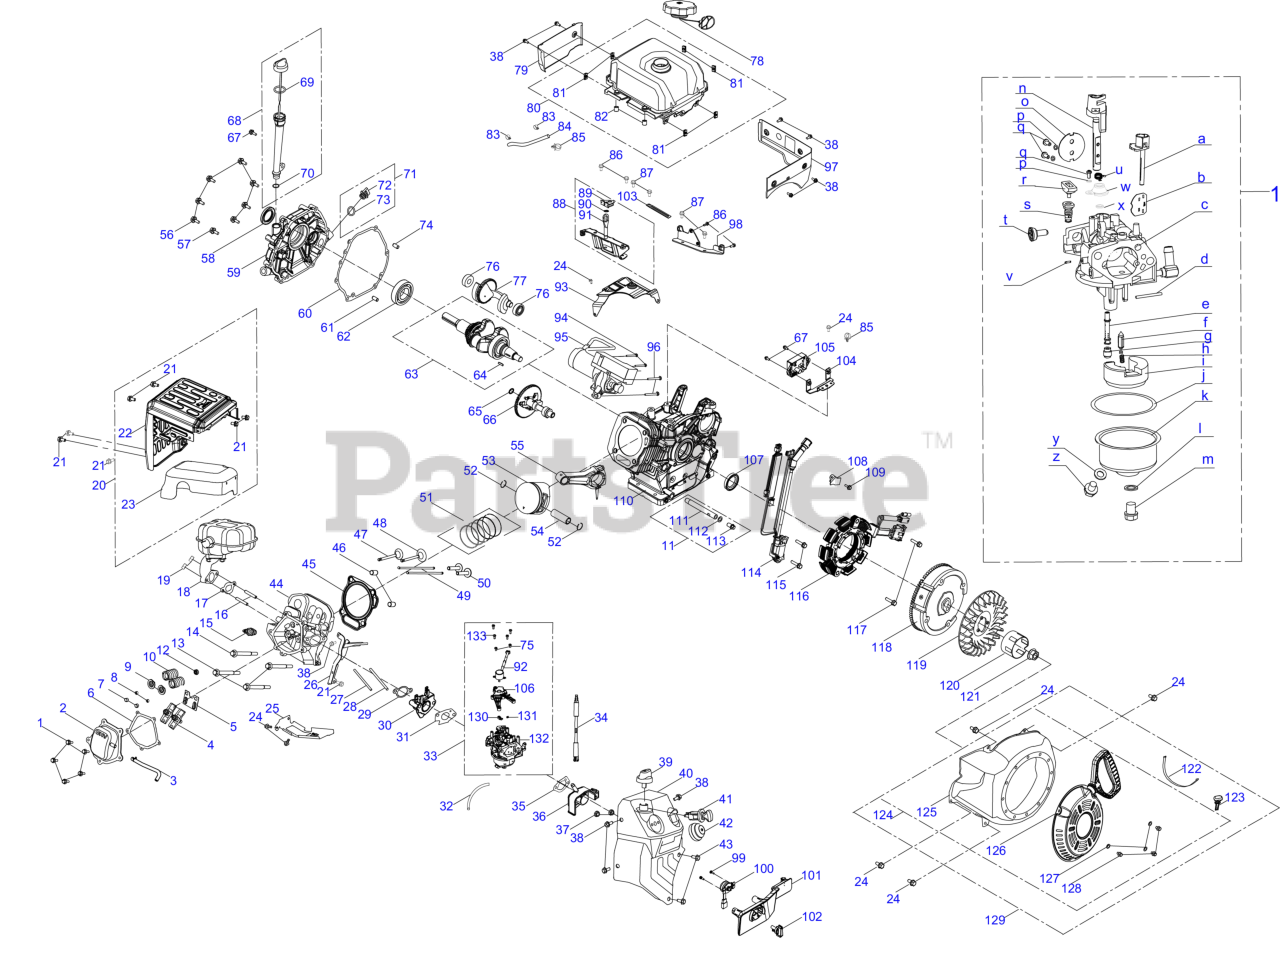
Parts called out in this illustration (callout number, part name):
1	BOLT M6 x 16
2	VALVE COVER
3	BREATHER HOSE
4	ROCKER ARM ASSEMBLY
5	PUSH ROD GUIDE
6	VALVE COVER GASKET
7	EXHAUST VALVE ADJUSTER
8	VALVE CAP
9	VALVE SPRING SEAT
10	VALVE SPRING
11	OIL DRAIN PIPE
12	INTAKE VALVE SEAL
13	SCREW M10-1.25 x 87 x GR10.9
14	SCREW M10-1.25 x 65 x GR10.9
15	SPARK PLUG (F6RTC/RN11YC/BPR6ES)
16	STUDS M8-1.25 x 48.5
17	MUFFLER GASKET
18	MUFFLER
19	NUT M8
20	MUFFLER GUARD
21	BOLT M6-1 x 10 GR8.8
22	MUFFLER SHIELD (OUTER)
23	MUFFLER SHIELD (INNER)
24	BOLT M6-1 x 12 GR8.8
25	CYLINDER BAFFLE
26	RECOIL SNOW GUARD
27	CARBURETOR STUD
28	STUD M6 x 123
29	CARBURETOR INSULATOR GASKET
30	INSULATOR
31	CARBURETOR INSULATOR GASKET
32	PRIMER HOSE
33	CARBURETOR
34	CHOKE KNOB SHAFT
35	HEATER BOX CARBURETOR GASKET
36	HEATER BOX
37	HEX NUT
38	BOLT M6-1 x 14 GR8.8
39	CHOKE KNOB
40	CONTROL PANEL
41	ENGINE KEY SWITCH ASSEMBLY
43	SCREW M6-1 x 20 CL5.8
44	CYLINDER HEAD (690-WU) ZS
45	CRANKSHAFT ASSEMBLY
46	DOWEL PIN
47	EXHAUST VALVE
48	INTAKE VALVE
49	PUSH ROD
50	TAPPET
51	PISTON RING KIT
52	PISTON PIN SNAP RING
53	PISTON
54	PISTON PIN
55	CONNECTING ROD ASSEMBLY
56	SCREW M8-1.25 x 38 GR10.9
57	BOLT M8 x 45
58	OIL SEAL
59	CRANKCASE COVER
60	CRANKCASE COVER GASKET
61	DOWEL PIN
62	BALL BEARING
63	CRANKSHAFT ASSEMBLY
64	WOODRUFF KEY
65	WASHER
66	CAMSHAFT
67	BOLT M6-1 x 18 GR8.8
68	DIPSTICK OIL ASSEMBLY
70	O-RING
71	OIL DRAIN PLUG
72	OIL PLUG
73	O-RING
74	DOWEL PIN
75	SCREW M4x8
76	BALL BEARING
77	BALANCE GEAR ASSEMBLY
78	FUEL CAP
79	FUEL TANK BACK PANEL
80	FUEL TANK ASSEMBLY
81	THREADED TAB
82	BUSHING
83	CARBURETOR HOSE CLAMP
84	FUEL HOSE
85	FUEL LINE SUPPORT CLAMP
87	BOLT M8-1.25 x 14 GR8.8
88	FUEL TANK MOUNTING BRACKET
89	RUBBER GROMMET
90	RUBBER GROMMET
91	FUEL TANK MOUNTING BRACKET
92	STEPPER MOTOR
93	GOVERNOR GEAR BRACKET
95	ELECTRIC STARTER
96	BOLT M8-1.25 x 55 GR8.8
97	FUEL TANK FRONT PANEL
98	FUEL TANK BASE BRACKET
100	SPEED CONTORL SWITCH
101	SPEED KNOB COVER
102	SPEED CONTROL KNOB
104	ECM BRACKET
106	MOTOR BASE
107	OIL SEAL
108	ALTERNATOR WIRE CLAMP BRACKET
109	BOLT M6-1 x 8 GR8.8
110	CRANKCASE
111	OIL DRAIN PIPE
112	FLAT WASHER
113	OIL DRAIN PLUG
114	IGNITION MODULE
115	IGNITION COIL BOLT M6-1 x 28 GR8.8
116	CHARGING COIL
117	BOLT-M6-1 x 30 GR8.8
118	FLYWHEEL
119	COOLING FAN
120	STARTER CUP
121	FLYWHEEL NUT M16X1.5
122	CABLE TIE - 3 x 150
123	IGNITION KEY
124	BLOWER HOUSING ASSEMBLY
125	BLOWER HOUSING
126	RECOIL START ASSEMBLY
127	FLAT WASHER
128	BOLT M6 x 10
129	RECOIL STARTER
130	GUIDE CLAMP
131	DAMPER SPRING
132	CARBURETOR
133	SCREW M4-0.7x10
